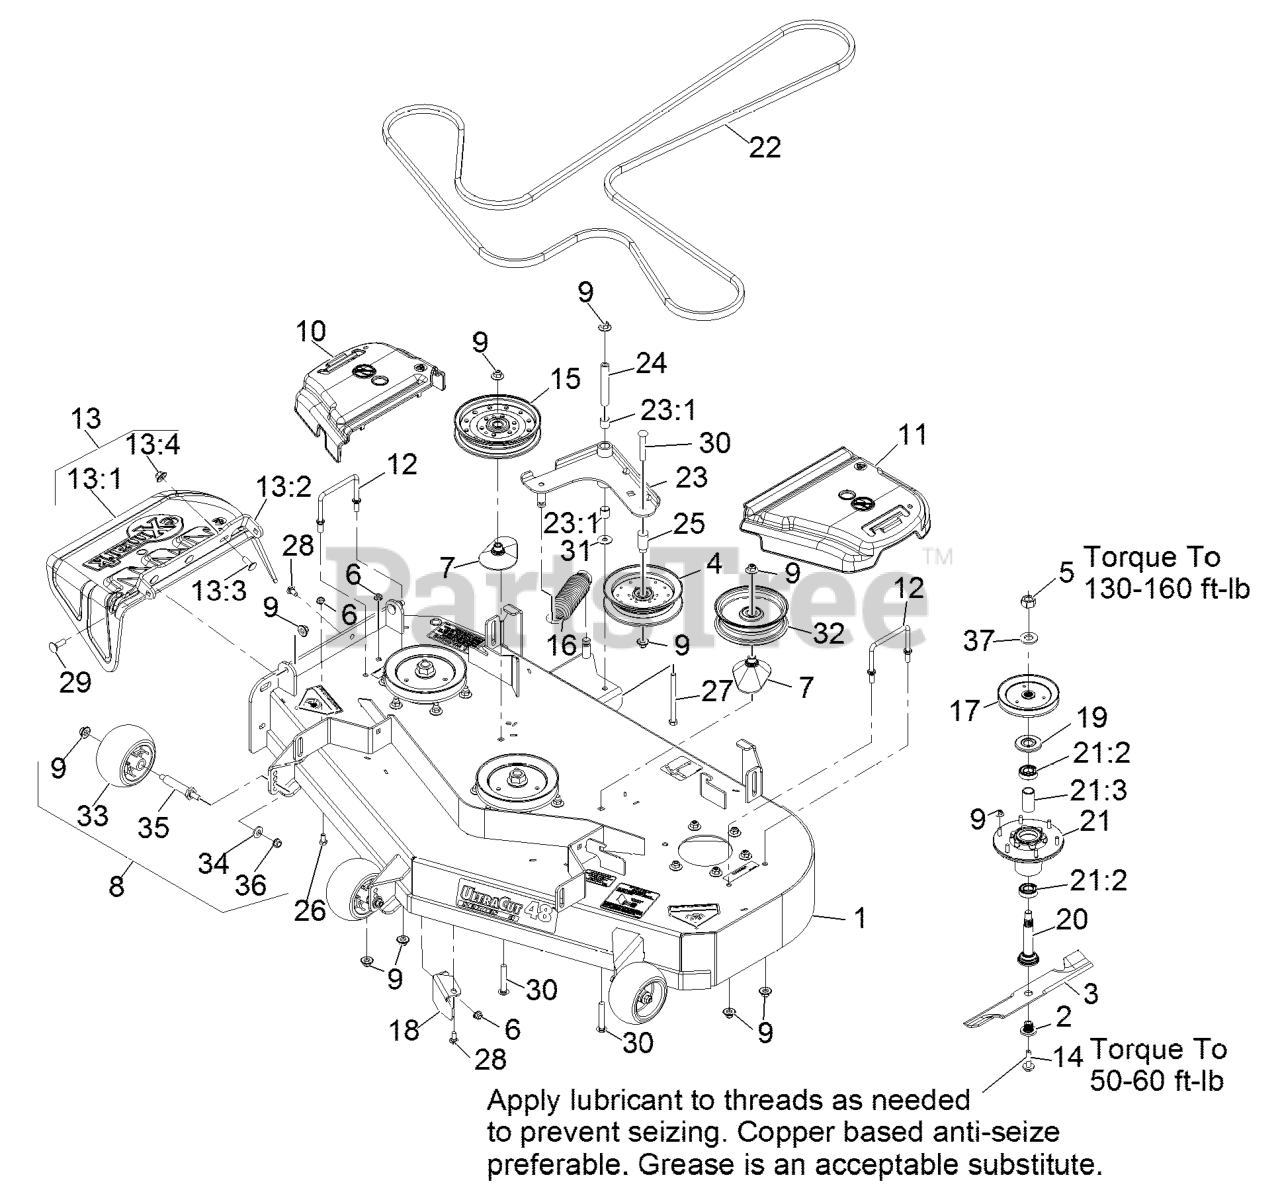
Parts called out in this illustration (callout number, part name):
1	ASM-DECK W/DECALS 48
2	BUSHING,SPLINED
5	NUT-HEX
6	NUT-HF, NI
7	SPACER-PULLEY
9	Nut-Nyloc 3/8-16 Flg
10	COVER-BELT, RH
11	COVER-BELT, LH
12	WIREFORM-COVER
13	ASM,DISCHARGE CHUTE
13:1	CHUTE,DISCHARGE
13:2	BRACKET,DISCHARGE CHUTE
13:3	SCREW-CARR
13:4	Nut-Nyloc 3/8-16 Flg
14	SCREW,SEMS 1/2-20 X 2.19
16	SPRING-EXTENSION
17	SHEAVE,BLADE DRIVE 5.90
18	BAFFLE,DISCHARGE 483
19	GUARD,BEARING TOP .989
20	ASM-SPINDLE AND SEAL
21	ASM-CUTTER HSG WITH BEARINGS
21:2	BEARING-BALL
21:3	SPACER-BEARING
22	BELT-B154.88
23:1	SLEEVE-BEARING
24	BUSHING
25	BUSHING-IDLER
26	SCREW-HH
27	SCREW-HH
28	BOLT-CARR
29	BOLT-CARR
30	SCREW-CARR
32	IDLER-PULLEY, FLAT
33	ROLLER-SCALP, ANTI
34	WASHER-BELLEVILLE
36	NUT-HHF, WHIZ
